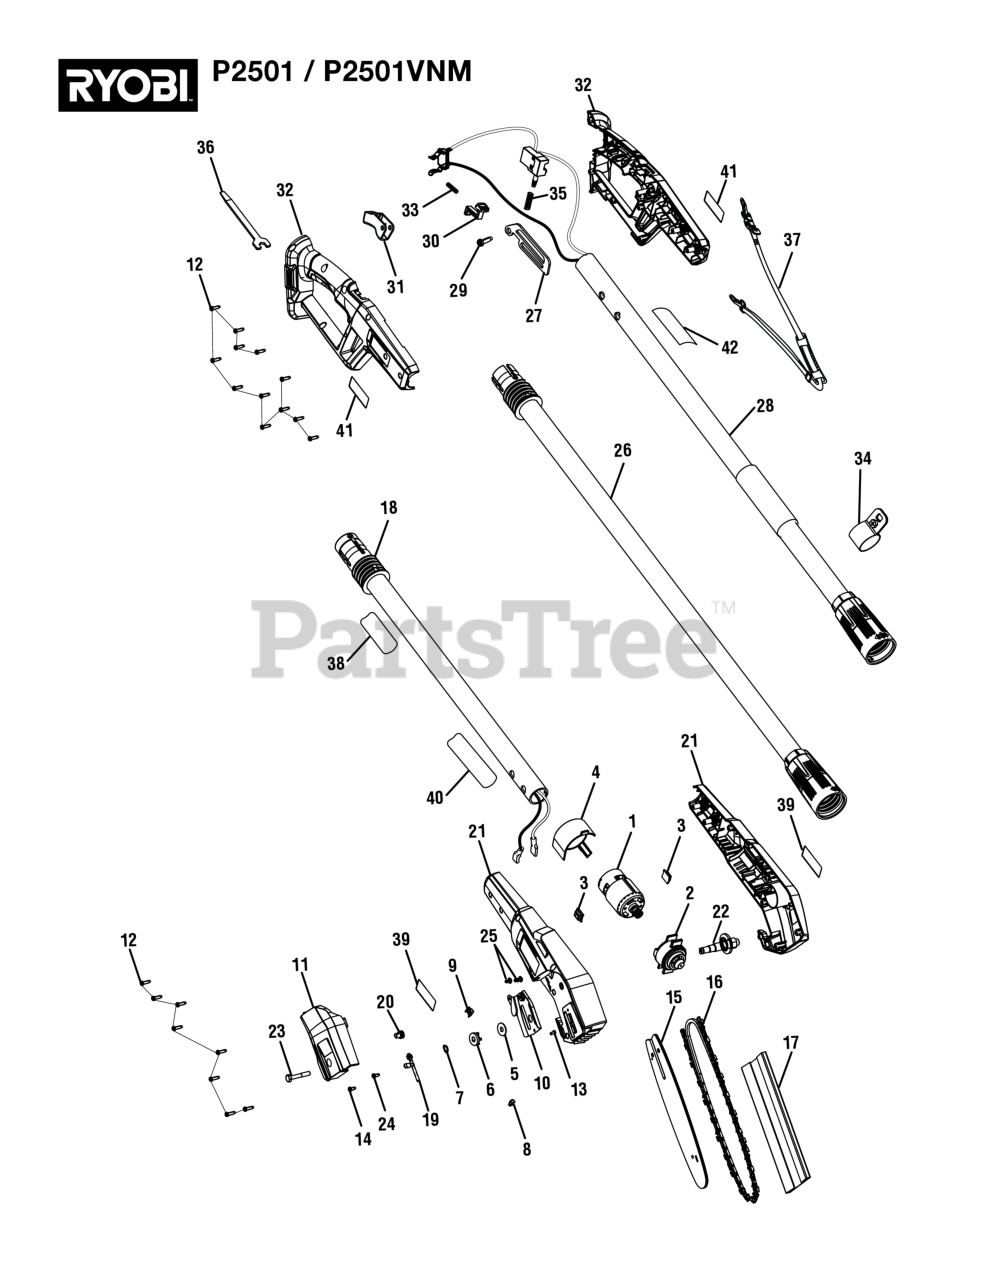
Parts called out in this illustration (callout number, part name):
1	Motor and Pinion Assembly
2	Output Gear Assembly
3	Rubber Bumper
4	Volute Cover
5	Cover Plate (Internal "D" Washer)
7	Retaining Ring
8	Small Pressure Plate
9	Big Pressure Plate
10	Guide Plate
11	Chain/Bar Cover
12	Screw (M4 x 14 mm, T15 Torx Pan Hd.))
13	Screw (M3 x 8 mm, T15 Torx Pan Hd.)
14	Screw (M3 x 10 mm)
15	Guide Bar
16	8 in. Saw Chain
18	Upper Pole Assembly (Inc Key Nos. 38 & 40)
19	Adjust Screw Assembly
20	Bar Adjust Gear
21	Motor Housing Assembly (Inc. Key No. 39)
22	Output Shaft Assembly
23	Screw with Spring Washer (M6 x 35 mm)
24	Screw (M4 x 8 mm, T15 Torx Pan Hd.)
25	Screw (M4x 7 mm, T20 Torx Hd)
26	Middle Pole Assembly
27	Strap Hanger
28	Lower Pole Assembly (Inc. Key Nos. 34 & 42)
29	Screw (M3 x 8 mm)
32	Rear Handle Assembly (Inc. Key No. 41)
33	Compression Spring (Trigger Lock)
34	Clamp Assembly
35	Compression Spring
37	Harness Assembly
38	Data Label
39	Motor Housing Logo Label
40	Warning Label (French/Spanish)
41	Handle Logo Label
42	Danger Icon Warning Label
